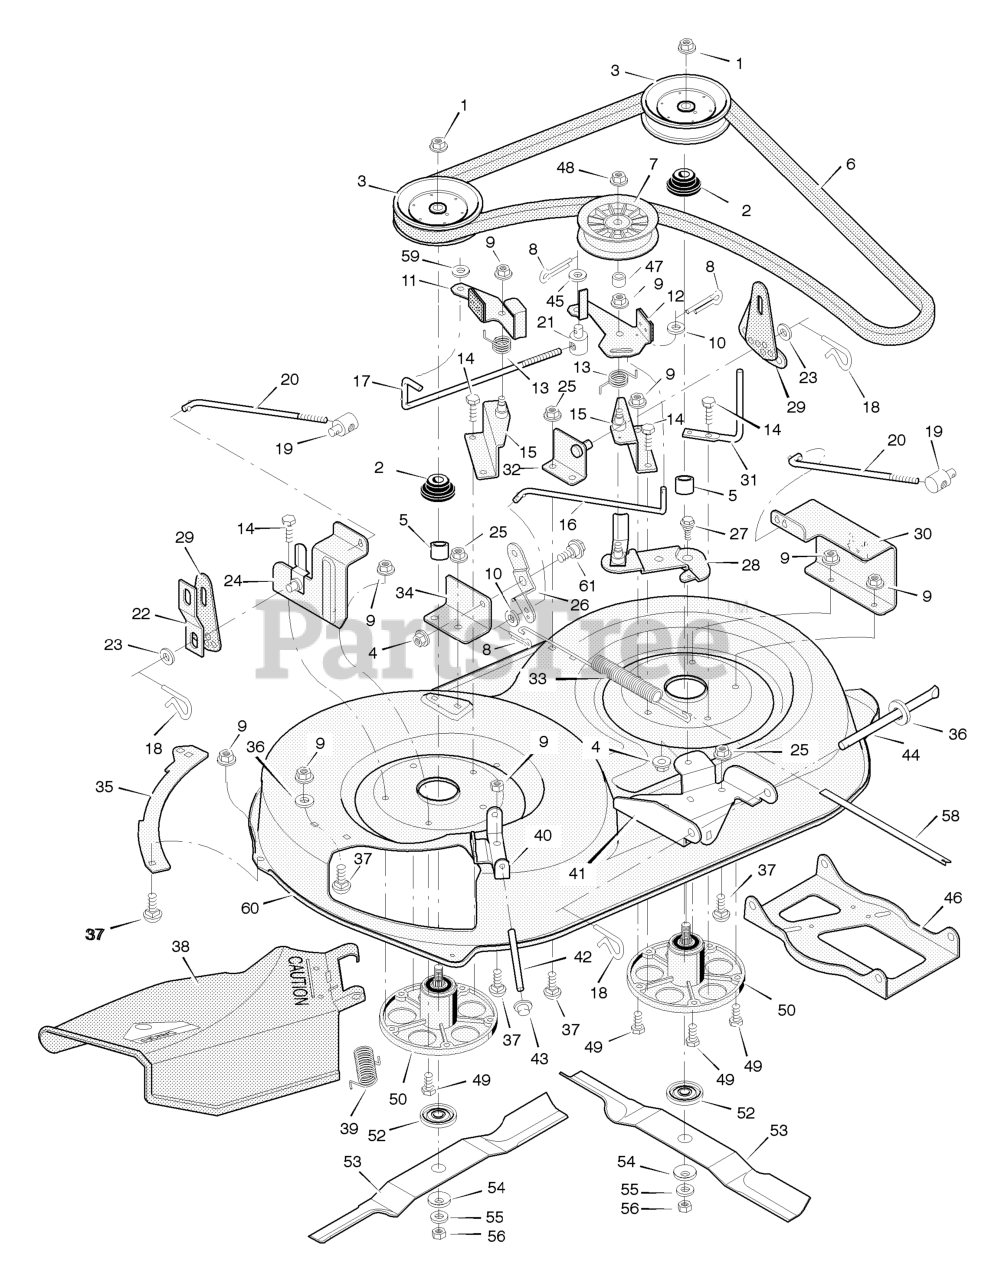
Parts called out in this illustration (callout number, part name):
1	Nut, Hex
2	Spacer
3	Pulley, Jackshaft
4	Locknut, Flange
6	Belt, Blade Drive
7	Pulley, Idler
8	Pin, Cotter
9	Locknut, Flange
10	Washer
11	Brake Assembly, Right
12	Brake Assembly, Left
13	Spring, Torsion
14	Bolt, Hex
15	Bracket Assembly, Brake
16	Rod, Brake
17	Rod, Cross Link
18	Pin, Hair
19	Nut, Adjustable
20	Rod, Adjuster
21	Nut, Adjustable
22	Link, Suspension
24	Bracket Assembly, Right Lifter
25	Nut, Flange
26	Crank, Bell
27	Bolt, Shoulder
28	Arm Assembly, Idler
29	Plate, Adjuster
30	Cover, Pulley
31	Guide, Belt
32	Bracket Assembly, Left Lifter
33	Spring, Extension
34	Bracket, Pivot
37	Bolt, Carriage
38	Deflector Assembly, Chute
39	Spring, Torsion
40	Bracket, Hinge
41	Bracket, Front Hanger
42	ROD, Deflector
43	Cap, Push On
44	Rod, Hanger
46	Hanger, Front
46	Suspension AVANT
48	Nut
49	CAPSCREW, Hex Head, 5/16-18 x 1
50	Housing, Jackshaft
52	Adapter, Blade
53	Blade, 38" (2 required)
53	Blade, 40" (2 required)
54	Washer, Belleville
56	Nut, Hex
58	Indicator, Plastic
60	Housing, Blade (38")
60	Housing, Blade (40")
61	Bolt, Shoulder
